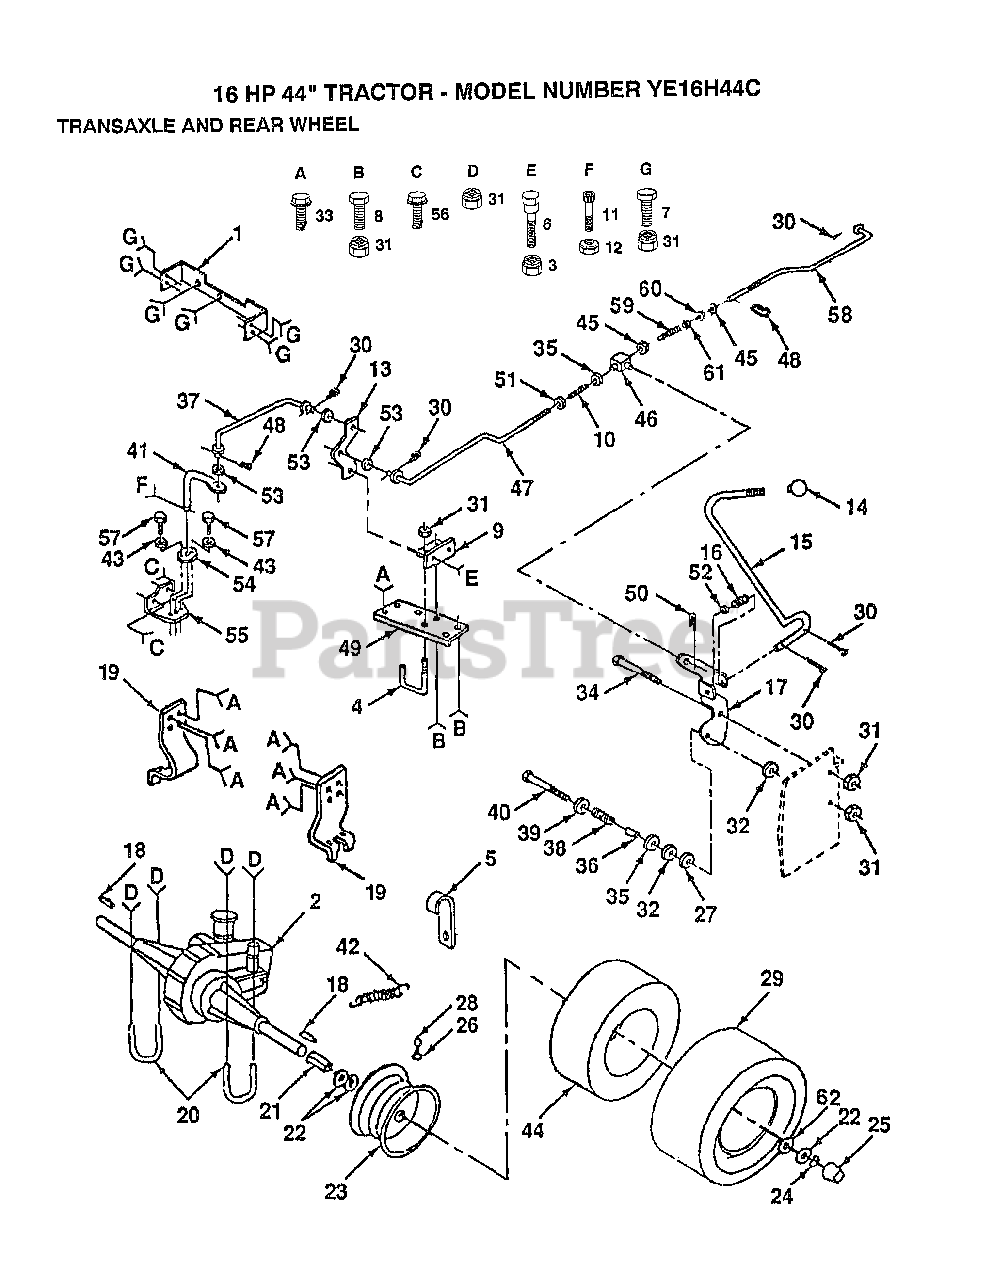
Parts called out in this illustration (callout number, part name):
1	PLATE TRANS SUPT
2	TRANSAXLE.AGRIFAB
4	KEEPER
5	CLIP T
6	SHOULDER BOLT LT
8	BOLT
9	BRKT BELLCRANK
10	SPRING GTV
11	SCREW
12	LOCKNUT
13	BELLCRANK
14	KNOB.DUCKHEAD.1/2
15	ROD.YTH
16	SPRING TORSION
17	BRKT CONTROL HYT
18	SQUARE KEY
19	BRKT TRANSAXLE
20	U BOLT
21	SPACER SPLIT
22	WASHER
24	E-RING LT
25	HUB CAP
26	VALVE STEM LT
27	WASHER HYT
28	VALVE CAP
30	COTTER PIN
32	WASHER FRIC HYT
33	SCREW
34	BOLT HYT
35	WASHER D
36	SPACER HYT
37	LINK CONTROL
38	SPRING HYT
39	WASHER
40	BOLT - HEX 3/8 - 16 X 3
41	ARM ASM PUMP
43	WASHER
44	TUBE.18X9.5-8
45	NUT
46	TRUNION HYT
47	ROD ADJ CONTROL
48	RETAINER M
49	BRACKET
50	SPRING.RETAINER
51	WASHER T
52	WASHER
53	WASHER T
54	GUIDE CONTROL
55	BRKT
56	SCREW
59	SPRING ROD LT
60	WASHER
61	NUT
62	WASHER
